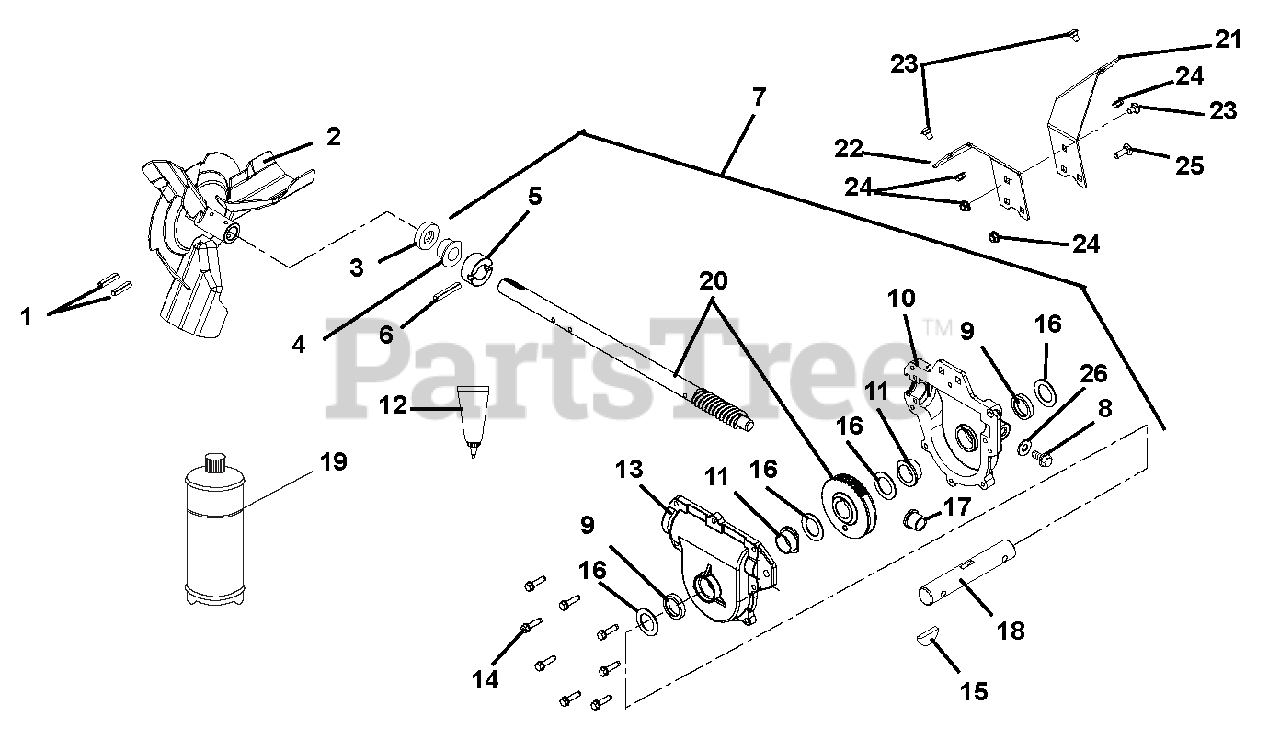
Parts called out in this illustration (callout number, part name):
1	PIN-ROLL .250X1.75
2	IMPELLER, 3 BLADE-14"
3	SEAL-OIL .875X1.375X.25 RBR OD
4	BSHG-FLG .876 X 1.500 X .750
5	THRUST COLLAR, .875" ID
6	PIN-GRV .250X1.50 TP E
7	GEAR CASE ASSEMBLY - COMMON
8	SCR-TAP .38-16X.75 ROLOK YZ WX
9	SEAL-OIL 1.000X1.375X.250
10	GEARCASE, ALUMINUM, LH
11	BSHG-FLG 1.003X1.5X.625
12	LOCTITE 518 GASKET--6ML TUBE
13	GEARCASE, ALUMINUM, RH
14	@SCR-TAP .25-20X1.00 HWH TR YZ
15	KEY-WDRF .25X.875 HRD #A
16	WSHR-FL-STL 1.010X1.505X.062YZ
17	BSHG-FLG .629 X 1.000 X .750
18	RAKE SHAFT, SHORT-COMMON
19	ARIENS L3 LUBE, 8 OZ BOTTLE
20	WORM SHAFT & GEAR
21	BRACKET, GEAR CASE SUPPORT-LH
22	BRACKET, GEAR CASE SUPPORT-RH
23	BLT-RDHDSQSHNK.31-18X.62 YZ-LK
24	@NUT-LK-TOP-FLG .31-18 YWZC
25	@BLT-RDHDSQNK .31-18X1.00 G5YZ
26	WSHR-FIBER .437X.656X.032
